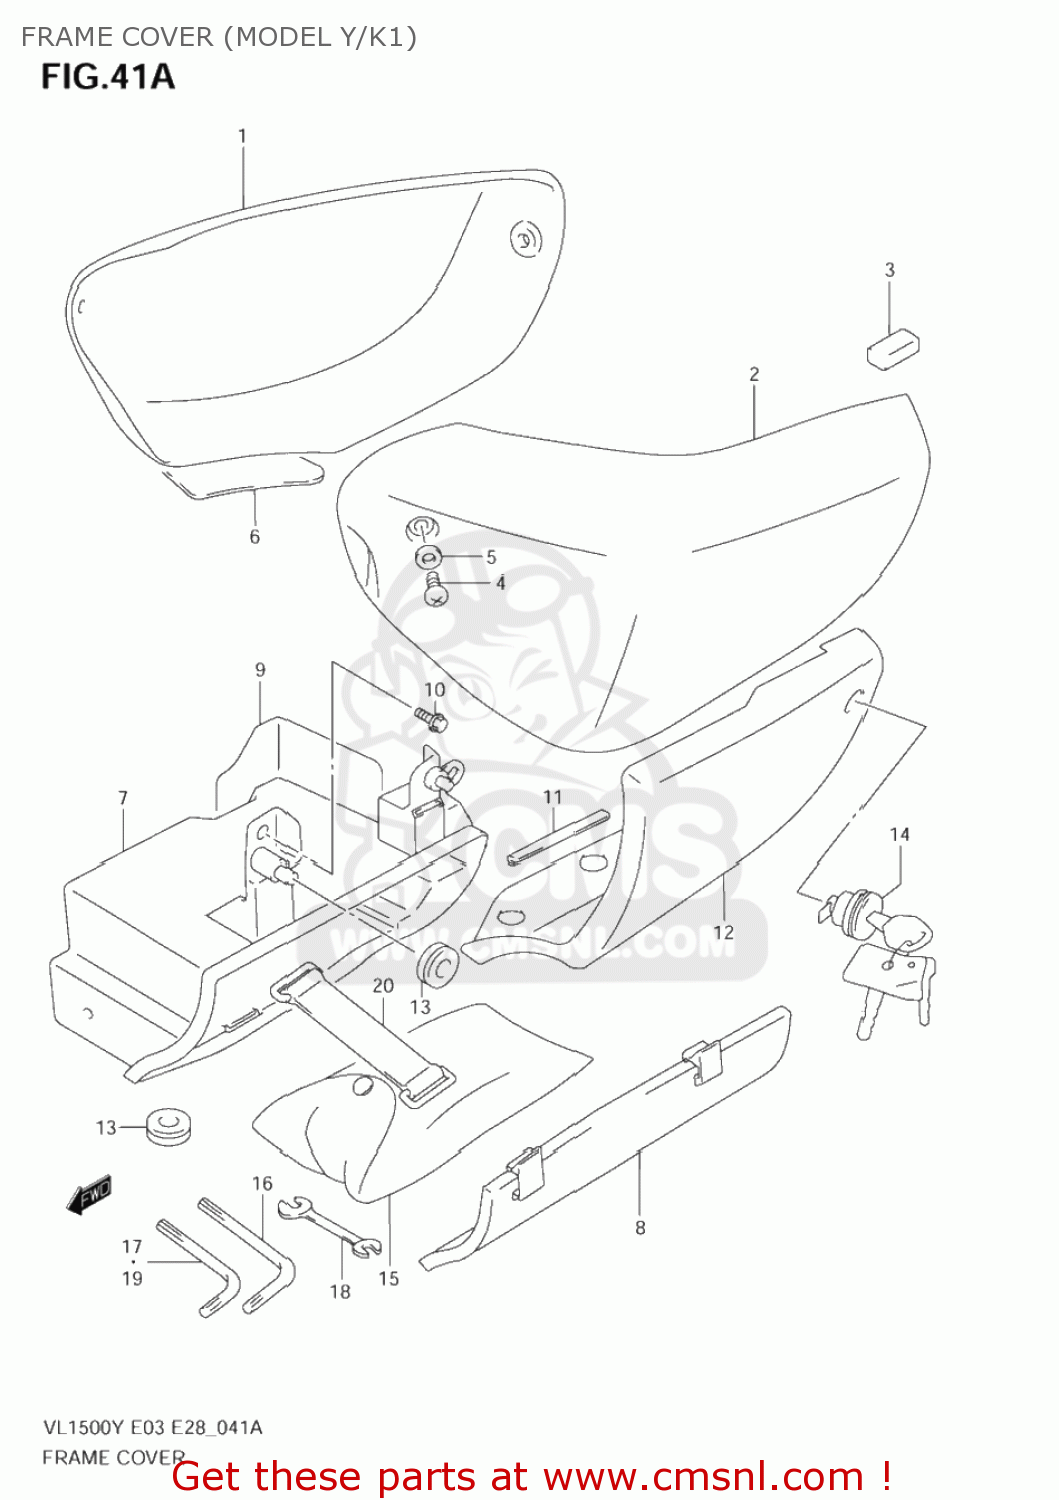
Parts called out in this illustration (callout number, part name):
1	COVER,FRAME,R(MAROON)
2	COVER,FRAME,L(MAROON)
3	CUSHION,FRAME COVER
4	SCREW(6X16)
5	WASHER(6.5X15X1.0)
6	SHIELD,FRAME COVER,R
7	BODY,TOOL HOLDER
8	CAP,TOOL HOLDER
9	SHIELD,TOOL HOLDER BODY
10	BOLT(6X16)
11	MOLDING,FRAME COVER,L
12	COVER,TOOL HOLDER
13	CUSHION
14	LOCK SET,COVER
15	TOOL ASSY
16	HEXAGON SPANNER,12
17	SPANNER,HEXAGON(4)
18	OPEN SPANNER(8X10)
19	HEXAGON SPANNER,5
20	BAND
